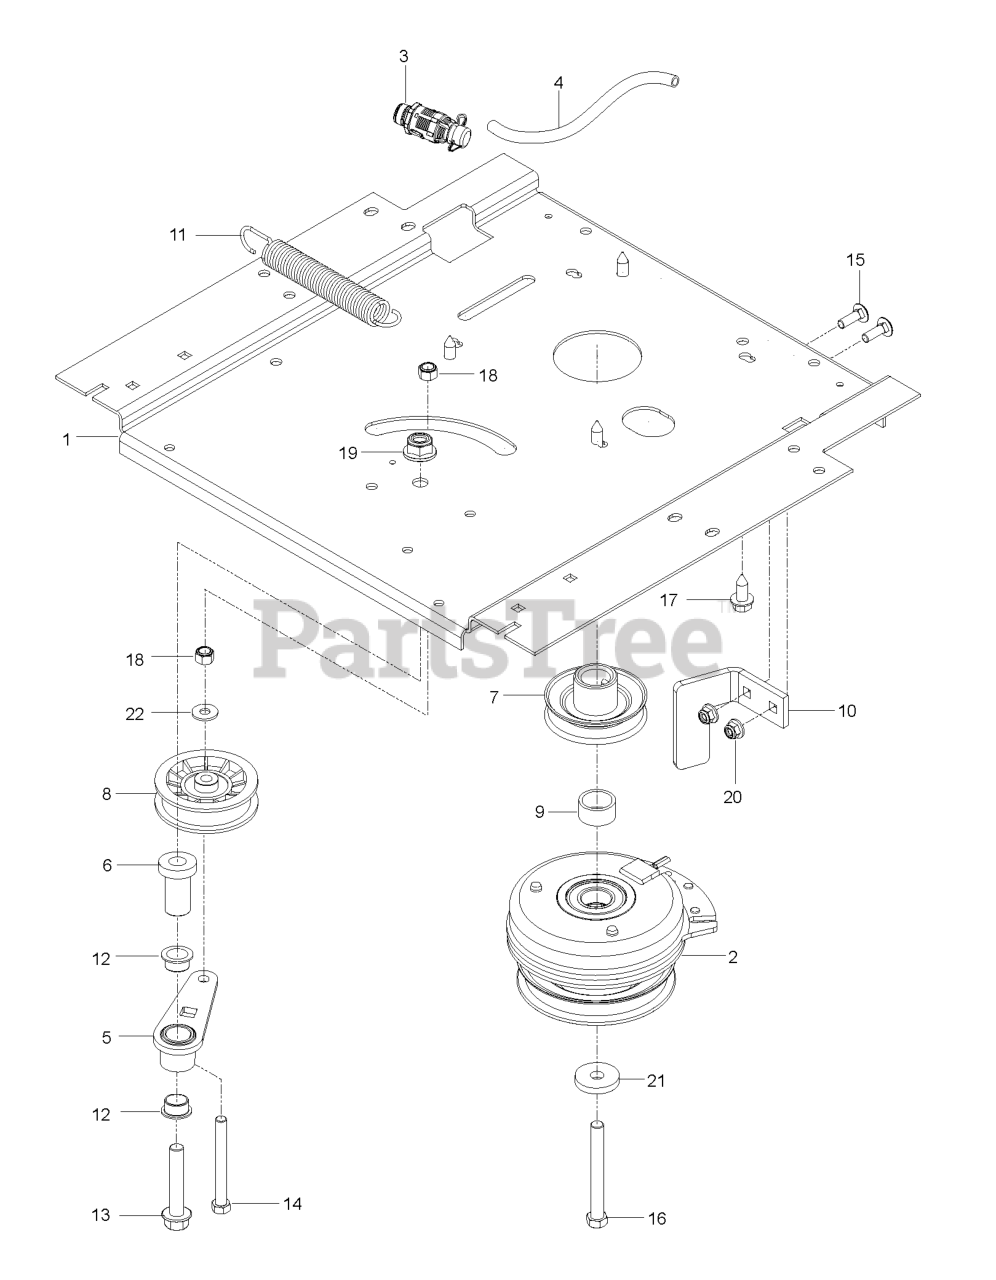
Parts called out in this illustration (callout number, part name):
1	PLATE ENGINE; RZ, 23IN BLACK
2	CLUTCH.105.FT-LBS
3	VALUE.OIL.DRAIN
4	TUBE, DRAIN OIL ASM.
5	ARM IDLER
6	SPINDLE.IDLER
7	PULLEY.ENGINE
8	PULLEY, IDLER
9	T & B SPACER
10	STOP, CLUTCH, BLACK
11	SPRING, DECK DRIVE
12	BEARING.FLANGED.PLASTIC.3/4ID
13	BOLT.FLANGE.1/2-13 X 2.75.GRD5
14	HCS 3/8-16X3-1/2 TAPBLT GR5 ZD
15	RHSNB 5/16C X 1
16	CLUTCH BOLT7/16-20X3.5 GR524HR
17	SCREW 3/8-16X1
18	NUT 3/8-16 NYLOC
19	NUT, 1/2-13 HEX FLG NYLOC ZD
20	5/16-18 NYLOC FLANGE NUT
21	Washer 1 - 1/2 OD x 15/32 ID x .250 (AYP part number)
22	Washer 3/8 x 7/8 x 14 Ga. (AYP part number)
